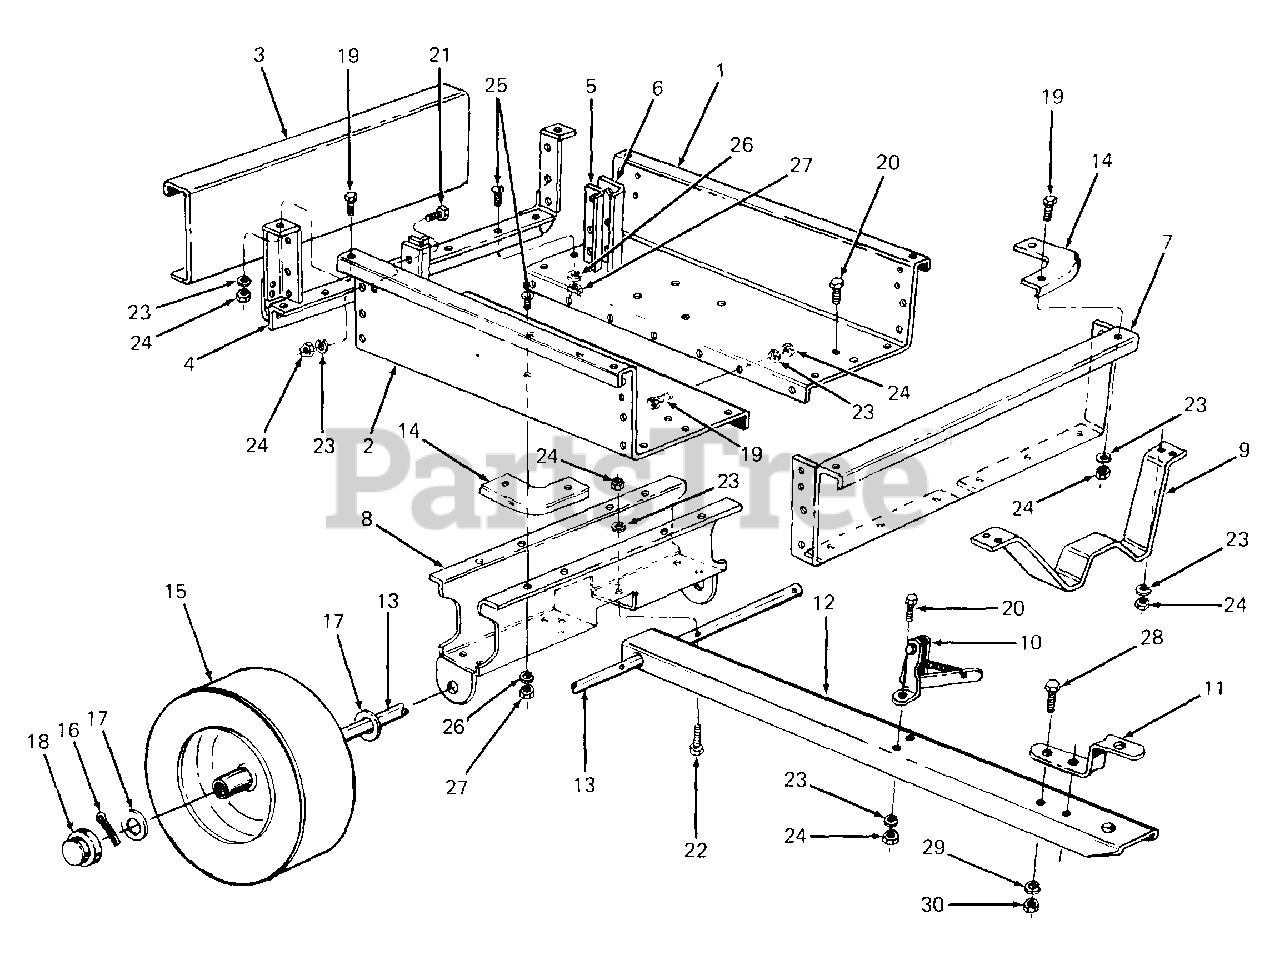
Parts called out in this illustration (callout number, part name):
6	Guide, Tailgate - Outside
17	Washer, Flat, 1.03 ID
18	Hub Cap
19	Screw, Hex Cap, 1/4-20 X .50 Lg
20	Screw, Hex Cap, 114-20 X .62 Lg
21	Screw, Hex Cap, 1/4-20 X .75 Lg
22	Screw, Hex Cap, 1/4-20 X 1.75 Lg
23	Washer, Lock, 1/4
24	Nut, Hex, 1/4-20
25	Screw, Truss Hd, 5/16-18 X .75 Lg
26	Washer, Lock, 5/16
27	Nut, Hex, 5/16-18
28	Screw, Hex Cap, 3/8-16 X 1.0 Lg
29	Washer, Lock, 3/8
30	Nut, Hex, 3/8-16
